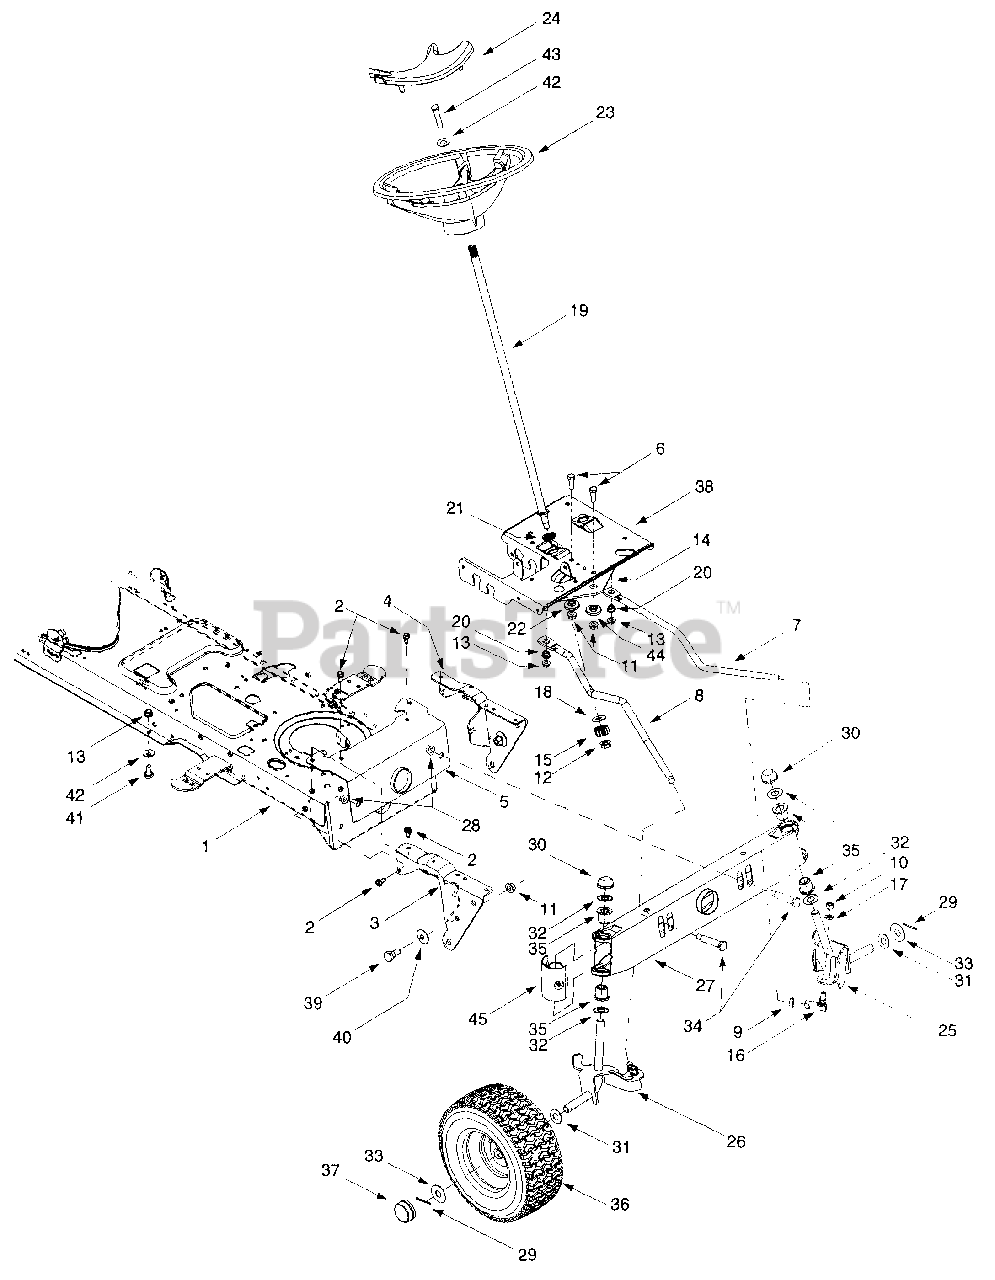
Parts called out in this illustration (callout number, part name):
6	Hex Cap Screw, 3/8-16 x 1 (Grade 5)
7	LH Drag Link
8	RH Drag Link
9	Jam Nut, 7/16-20 (Grade 2)
10	Hex Nut, 3/8-24 (Grade 2)
11	Flange Lock Nut, 3/8-16
12	Flange Lock Nut, 7/16-20
13	Flange Lock Nut, 5/16-18
14	Steering Gear, 11/90 Ratio
15	Steering Pinion Gear
16	Ball Joint, 7/16-20
17	Lock Washer, 3/8
18	Flat Washer, .51 x 1.12 x .06
19	Steering Shaft, .625 OD x 24.4
20	Plastic Bushing, .38 ID
21	Hex Flange Bearing, 5/8
22	Shoulder Spacer, .38 ID
23	Steering Wheel
24	Steering Wheel Cap w/ Logo
25	LH Axle Assembly, .625 Diameter
26	RH Axle Assembly, .625 Diameter
28	Flange Lock Nut, 3/8-16
29	Cotter Pin
30	Push Cap, 5/8
31	Flat Washer, .64 x 1.0 x .12
32	Flat Washer, .64 x 1.24 x .06
33	Flat Washer, .635 x 1.589 x .06
34	Shoulder Screw, .5 x 2.2, 3/8-16
35	Flange Bearing, .632 ID x .937 OD
39	Shoulder Screw, .625 x .50, 7/16-20
40	Bell Washer, .39 x 1.13 x .062
41	Shoulder Screw, .435 x .178, 5/16 x .56
42	Bell Washer, .34 x .872
43	Hex Bolt, 5/16-18 X 1
44	Shoulder Spacer, .38 ID
45	Pivot Bar End Cap
